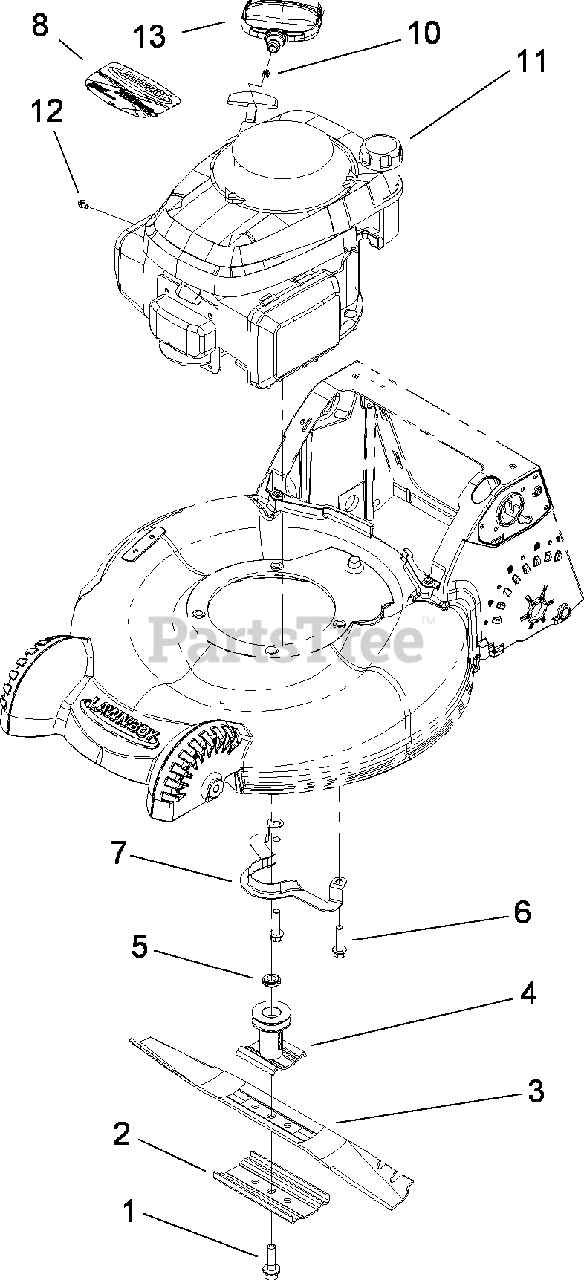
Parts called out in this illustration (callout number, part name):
1	BOLT-BLADE
2	SUPPORT-BLADE
3	BLADE-21 INCH
4	BLADE DRIVER ASM
5	Spacer-Driver
6	SCREW-HWH
8	DECAL-ENGINE
10	STOP-ROPE
12	SCREW-HWH
13	HANDLE-RECOIL
